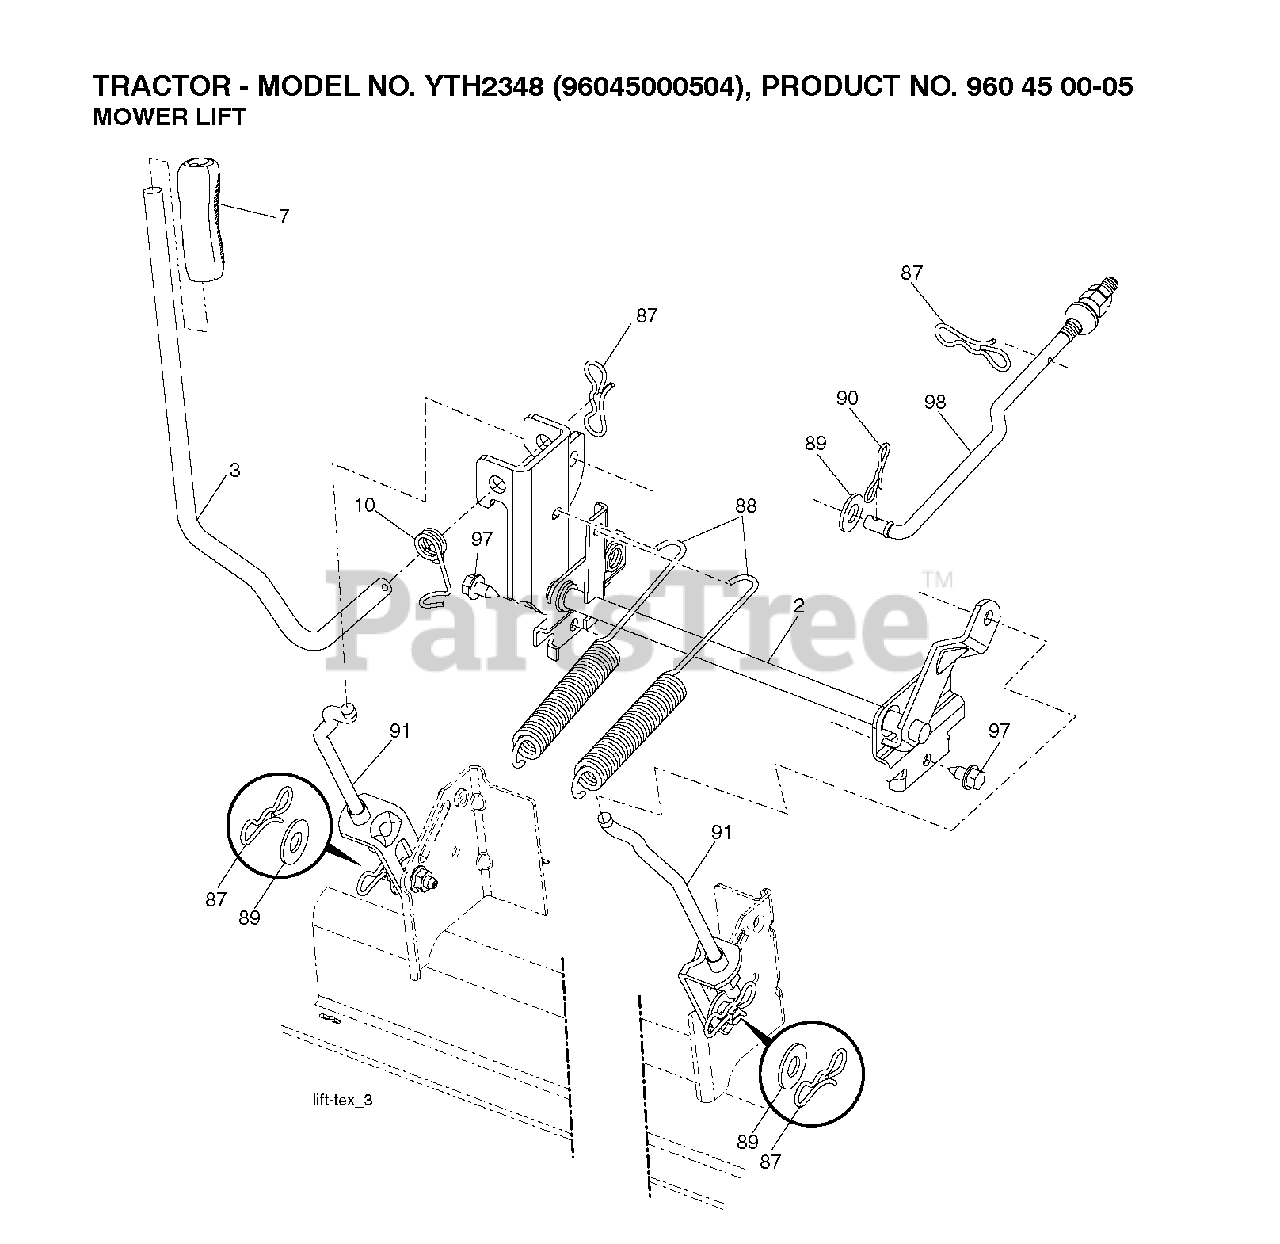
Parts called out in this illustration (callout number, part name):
2	SHAFT.ASM.LIFT.CROSS.H
3	LEVER.LIFT.HANDLE.LT
7	GRIP.HANDLE.LIFT.PVC.BLACK
10	SPRING.TORSION.LIFT.HANDLE
87	PIN.COTTER.7/16.BOW TI.
88	SPRING.LIFT.ASSIST
89	WASHER.CLEAR.ZINC
90	PIN.COTTER.5/16.BOW TI
91	LINK.ASM.LIFT.REAR
97	SCREW, 3/8-16X3/4
98	LINK.ASM.SUSP.FRONT.MWR.10.5
